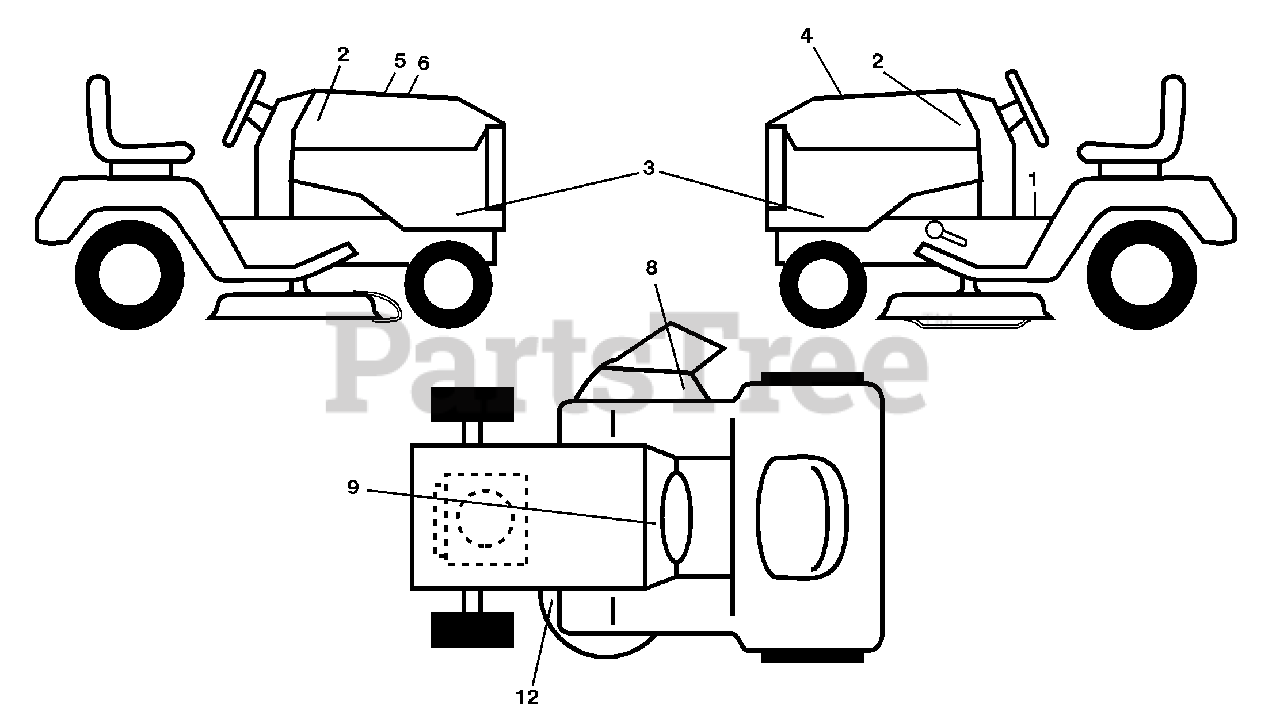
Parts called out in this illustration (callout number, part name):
1	Decal, Operators
2	Decal, Hood
3	Decal, Emblem Panel SD
4	Decal, Engine
5	Decal, Customer Respons.
6	Decal, Replacement
8	Decal Mower Warn Keep Hand away
9	Decal, Battery Dnge/Poi
12	Decal, Mower V-Belt Schematic
12	Decal, Deck Air Induct
12	Decal, Bypass
12	Pad, Footrest, LH
12	Pad, Footrest, RH
12	Manual, Owner's
